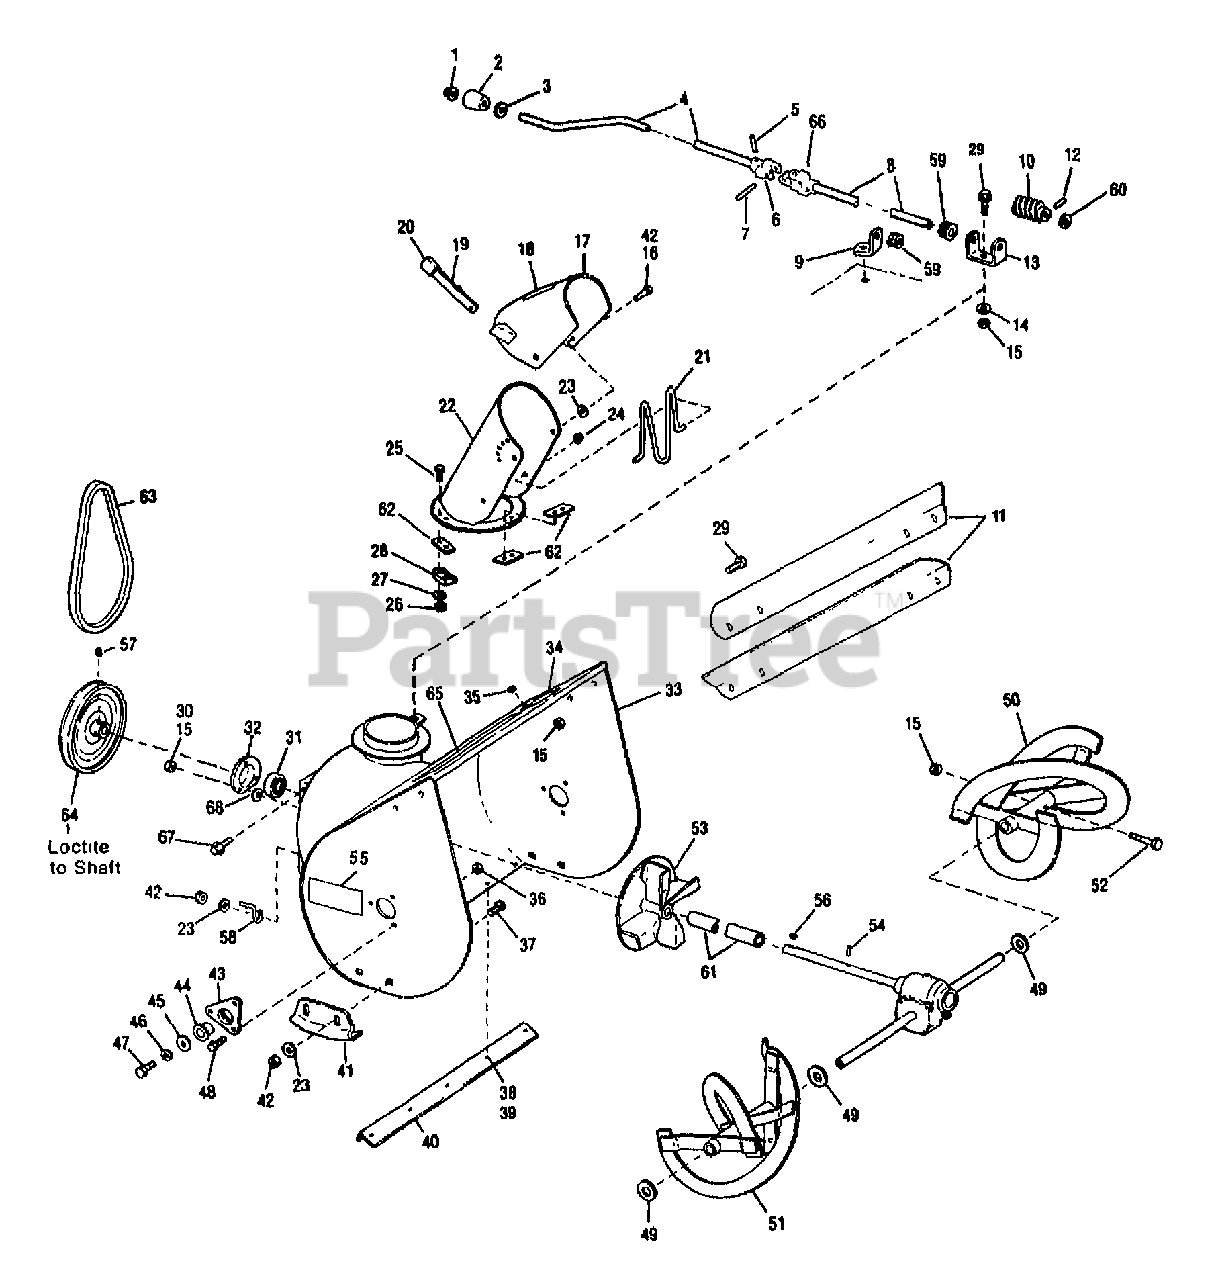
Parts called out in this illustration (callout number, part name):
1	NUT-PUSH 3/8 ZP
2	KNOB
3	WASHER-FLAT .375DIA
4	CRANK-CHUTE CONTROL
5	PIN-ROLL .156X.75
6	ASSM-U JOINT
7	PIN-ROLL .156X1.0
8	SHAFT-CHUTE CONTROL
9	CRANK SUPPORT
10	GEAR-WORM LH
11	KIT-SLICER DRIFT (2)
12	PIN-DRIVE .09X.75
13	SUPPORT-GEAR
14	WASHER-FLAT 5/16 SAE
15	NUT-TOP/LK 5/16-18 ZP
16	SCR-HH 3/8-16X.75 G5 ZP
18	DECAL-WARNING
19	LEVER-ADJUSTING
20	GRIP-VACUCUT
21	GUARD-CHUTE
22	ASSM-CHUTE @DEPL1771723010
23	WASHER-FLAT 3/8 SAE
24	NUT-PUSH 3/16
25	SCR-HW M10-24X.88 EXTTOOTH
26	NUT-H/LK M10-24 NYLOCK
27	WASHER-.505X.22X.05
28	CLIP-HOLD DOWN
29	SCR-HFLK 5/16-18X.75 ZP
30	SCR-HH 5/16-18X.63 G5
31	BEARING-BALL
32	RETAIN-BEARING
33	HOUSING ASSY
34	DECAL-WARNING
36	NUT-HT LK 1/4-20
37	BOLT-3/8-16 X 3/4
38	NUT-HFLK 5/16-18 ZP
39	SCR-CARR 5/16-18X.50 G5 ZP
40	BLADE-SCRAPER
41	RUNNER-SKIP
42	NUT-LOCK 3/8-16
43	SUPPORT-BEARING
44	BUSHING-FLANGE
45	WASHER-1/2 FLAT
46	WASHER-LK .5
47	SCR-HH 1/2-13X.75 G5 ZP
48	SCR-HH 1/4-20X.625 G5 ZP
49	WASHER-SPEC
50	ASSM-AUGER BLADE LH
51	ASSM-AUGER BLADE RH
52	SCR-SHEAR 5/16-18X1.75
53	ASSM-IMPELLER
54	PIN-ROLL 1/4 X 1-1/4
55	DECAL-HOUSING SIDE
56	KEY-WOODRUFF .188X.75
57	SCR-SET SQ 5/16-18X5/8
58	GUIDE-BELT
59	BUSHING-NYLON
60	WASHER-BOW .75X.385X.01
61	SLEEVE
63	BELT-V 36.00
64	SHEAVE-AUGER DRIVE
65	DECAL-LOGO
66	U-JOINT YOKO
67	SCR-HFLK 5/16-18X.75
68	SHIM-1.75X1.26X.02
